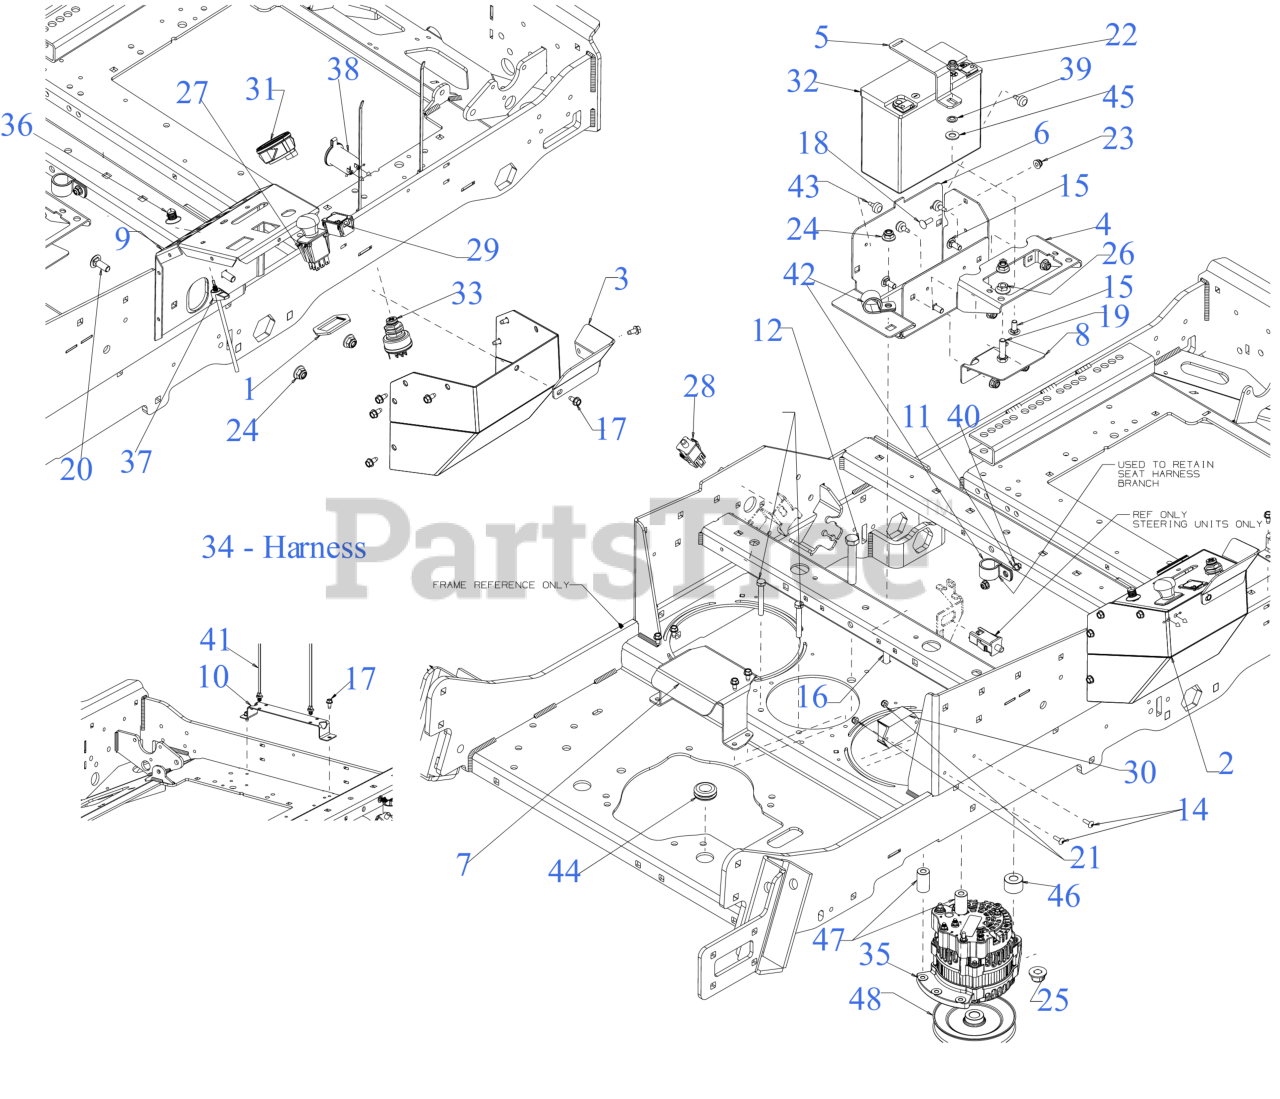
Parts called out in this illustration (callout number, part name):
1	BRACKET-PTO SWITCH
4	FUSE/RELAY MOUNT BRACKET
5	BATTERY SUPPORT BRACKET
6	BATTERY MOUNT BRACKET
7	ALTERNATOR COVER BRACKET
8	HARNESS GUARD PLATE
9	CONTROL POD (RH)
10	HARNESS GUIDE BRACKET
11	CARRIAGE BOLT 1/4-20 x .62
12	SCREW-HEX 1/2-13 x 3.00
13	HEX SCREW 5/16-18 x 2.25 GR5
14	SCREW #10-24 x .62
15	CARRIAGE BOLT 5/16-18 x .75
16	CARRIAGE BOLT 3/8-16 X1.25 GR5
17	SCREW 1/4-20 X.500
18	SCREW 1/4-20 x .75 GR5
19	SCREW 3/8-16 x 1.25 GR5
20	CARRIAGE BOLT 3/8-16 x 1.00 GR5
22	FLANGE LOCK NUT 5/16-18
23	FLANGE LOCK NUT
26	FLANGE LOCK NUT
27	PTO SWITCH (BLACK KNOB) TEXT SYM
28	3 POLE SWITCH ( NC-NO-NO)
30	CONTROL PANEL (SOFT CLUTCH)
31	DUAL FUEL GAUGE
32	BATTERY (300 CCA)
33	KEY SWITCH
34	INTERLOCK SWITCH (NO/NC)
34	3 POLE SWITCH ( NC-NO-NO)
34	NEUTRAL SWITCH
35	ALTERNATOR 70A
37	ROTARY SWITCH
38	POWER RECEPTICAL
40	RETAINER-BOLT .25ID x .50OD
41	CABLE TIE
42	HOSE CLAMP 1.0"
43	BUMPER, .62 DIA x .3
44	RUBBER GROMMET
45	FLAT WASHER
46	SPACER (LARGE)
47	SPACER (SMALL)
